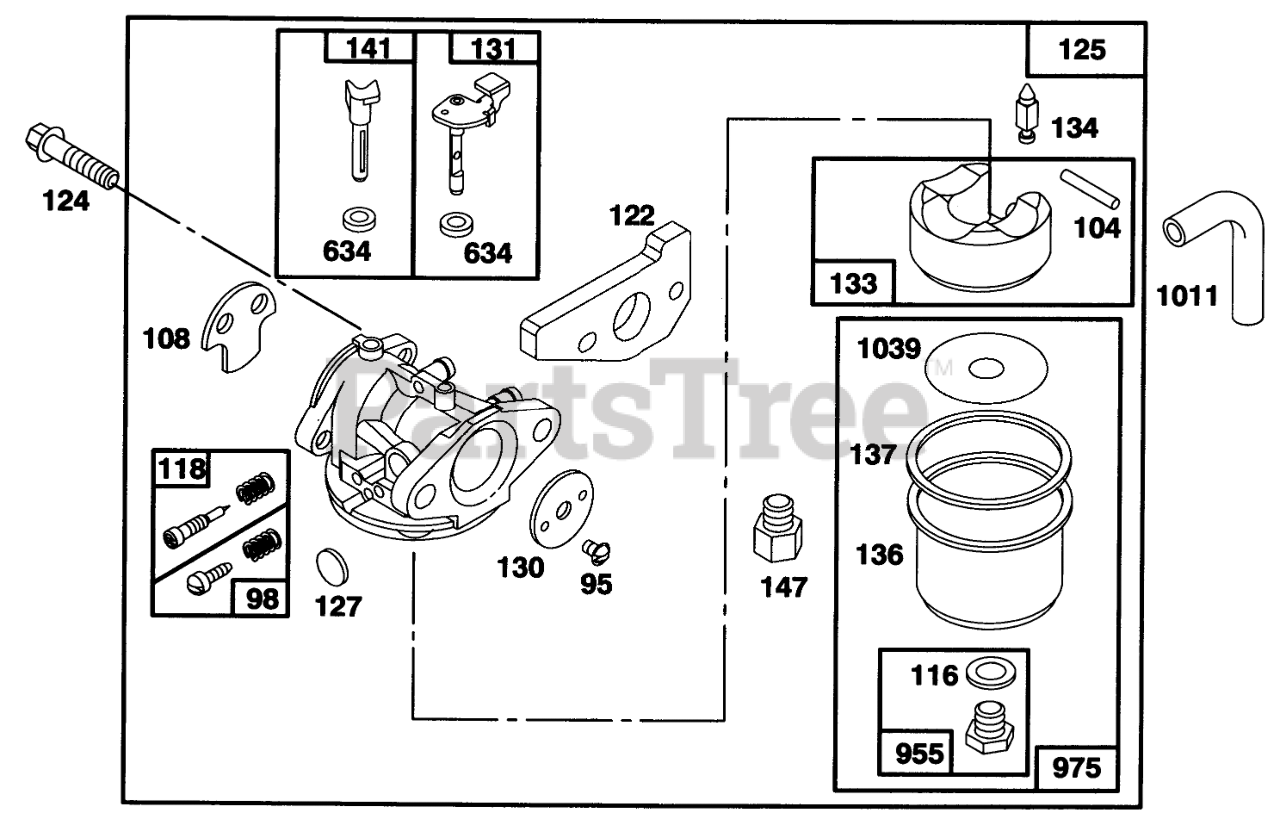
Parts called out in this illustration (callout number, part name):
95	SCREW - ROUND HEAD
98	IDLE ADJUSTING SCREW
104	FLOAT HINGE PIN
108	CHOKE VALVE
116	SEALING GASKET
118	VALVE KIT - NEEDLE
122	ADAPTER ASSEMBLY
124	HEX HEAD SCREW
125	CARBURETOR ASSEMBLY
127	PLUG
130	THROTTLE VALVE
131	THROTTLE SHAFT
133	FLOAT-CARBURETOR
134	Valve-Inlet (Includes Seat)
136	FLOAT BOWL
137	FLOAT BOWL GASKET
141	CHOKE SHAFT
147	JET ADAPTER
634	SEAL WASHER
955	HEX HEAD SCREW
975	CARBURETOR BOWL ASM
1011	VENT TUBE
1039	FLOAT LIMITER
